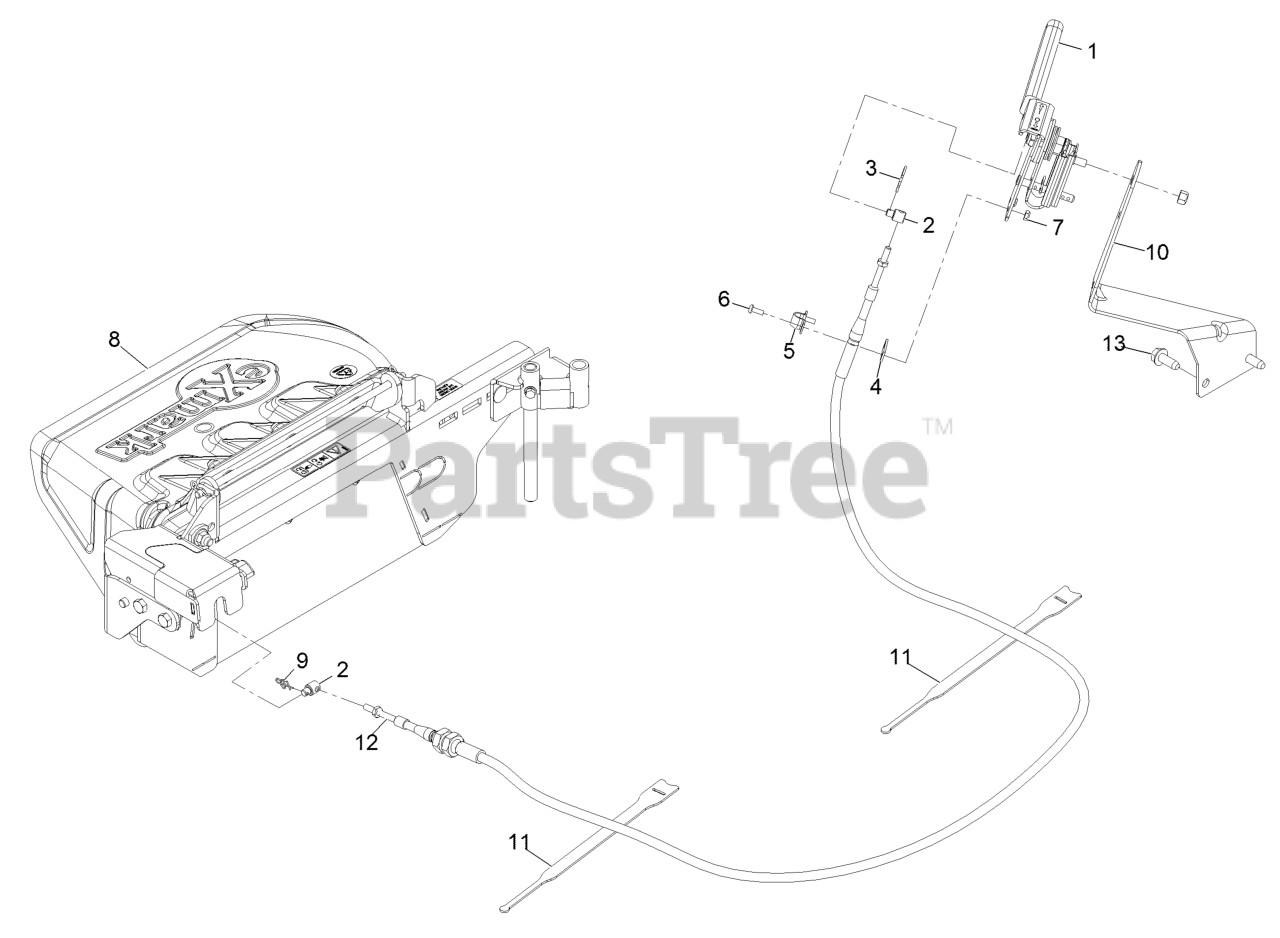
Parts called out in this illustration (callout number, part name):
1	ASM, HAND LEVER
2	PIVOT, CONTROL CABLE
3	PIN-COTTER
4	SHIM,CONTROL CABLE
6	SCREW-PPH
7	NUT-LOCK, NI
8	ASM, OCD
9	PIN-COTTER, LOCKING
10	BRACKET-SUPPORT OCDC
11	STRAP-VELCRO, CABLE TIE
12	CABLE-DISCHARGE GATE
13	SCREW-FORMING, THREAD
